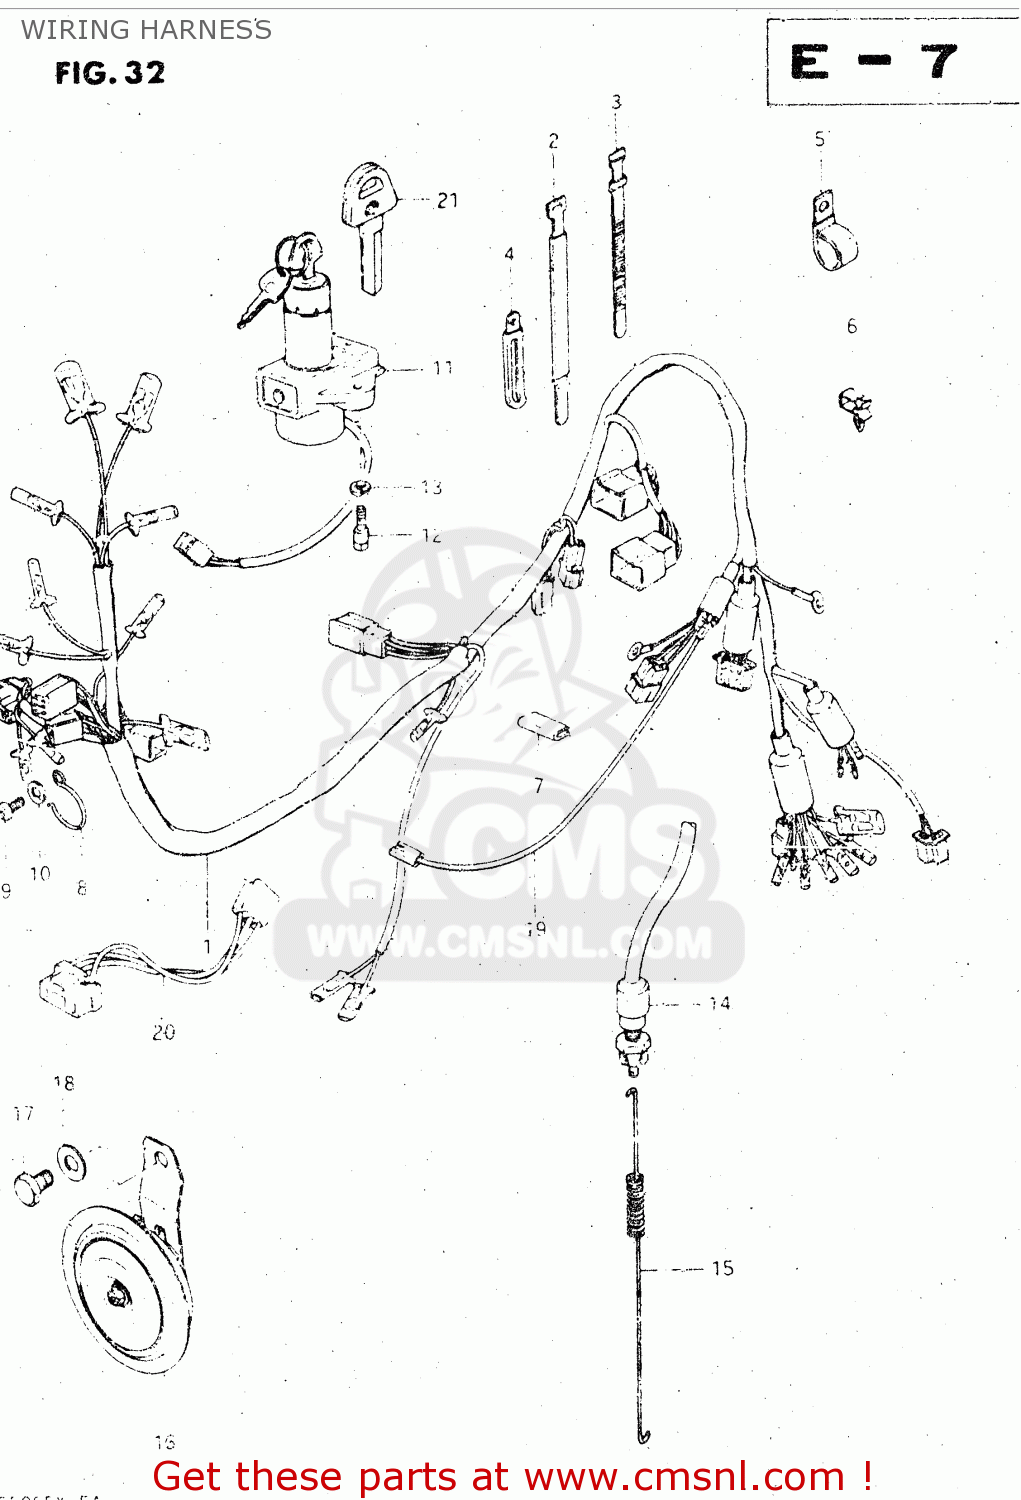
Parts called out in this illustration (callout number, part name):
1	WIRING HARNESS
2	CLAMP
3	CLAMP(L:120)
4	CLAMP
5	CLAMP
6	CLIP
7	PROTECTOR,WIRING HARNESS
8	GUIDE,WIRING HARNESS
9	SCREW 6X12
10	WASHER
11	LOCK ASSEMBLY,STEERING
12	BOLT
13	LOCK WASHER
14	SWITCH ASSEMBLY,STOP LAMP
15	SPRING
16	HORN ASSEMBLY
17	BOLT 8X12
18	WASHER
19	WIRE
20	LEAD WIRE,HEADLAMP
21	KEY,BLANK
